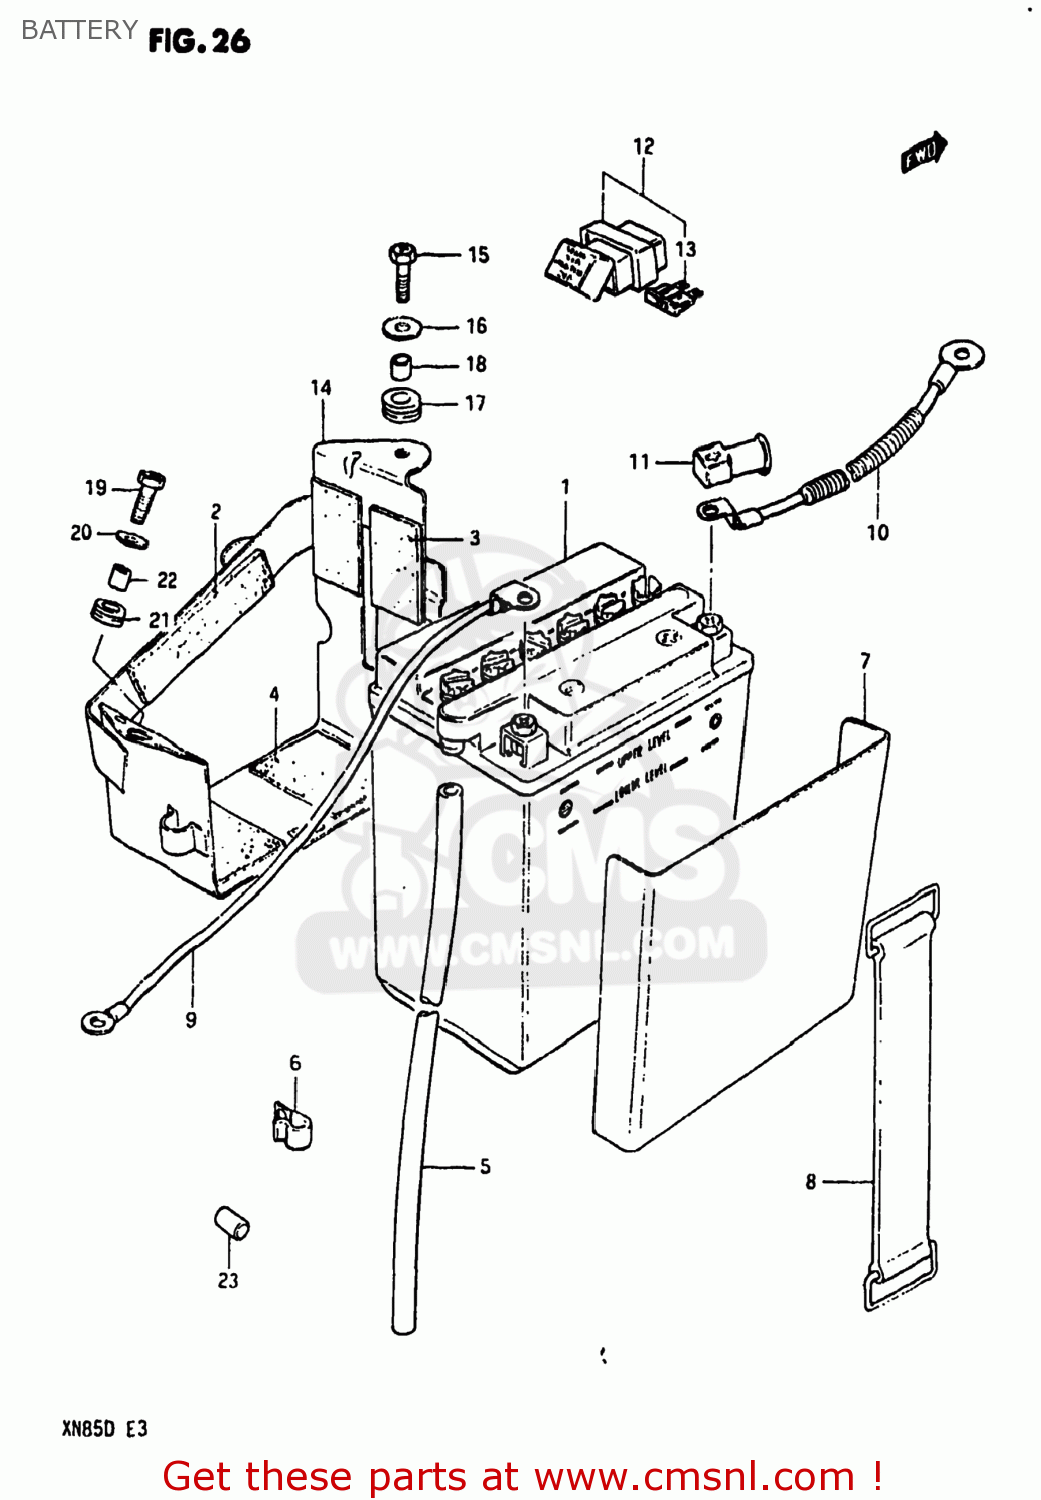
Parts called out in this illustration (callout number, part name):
1	BATTERY ASSY (12V)
2	PROTECTOR(20X90)X4
3	CUSHION(30X50X3)
4	PROTECTOR,BATTERY
5	HOSE,BATTERY EXHAUST
6	CLAMP
7	COVER,BATTERY
8	BAND
9	WIRE,STARTER MOTOR LEAD
10	WIRE,BATTERY PLUS
11	CAP,BATTERY PLUS TERMINAL
12	BOX ASSEMBLY,FUSE
13	FUSE(20A)
14	HOLDER,BATTERY
15	BOLT L:16
16	WASHER (6.5X24X1.6)
17	CUSHION
18	SPACER(6.2X8.3X6.1)
19	BOLT L:16
20	WASHER
21	CUSHION
22	SPACER(6.1X9X7.5)
23	CUSHION
